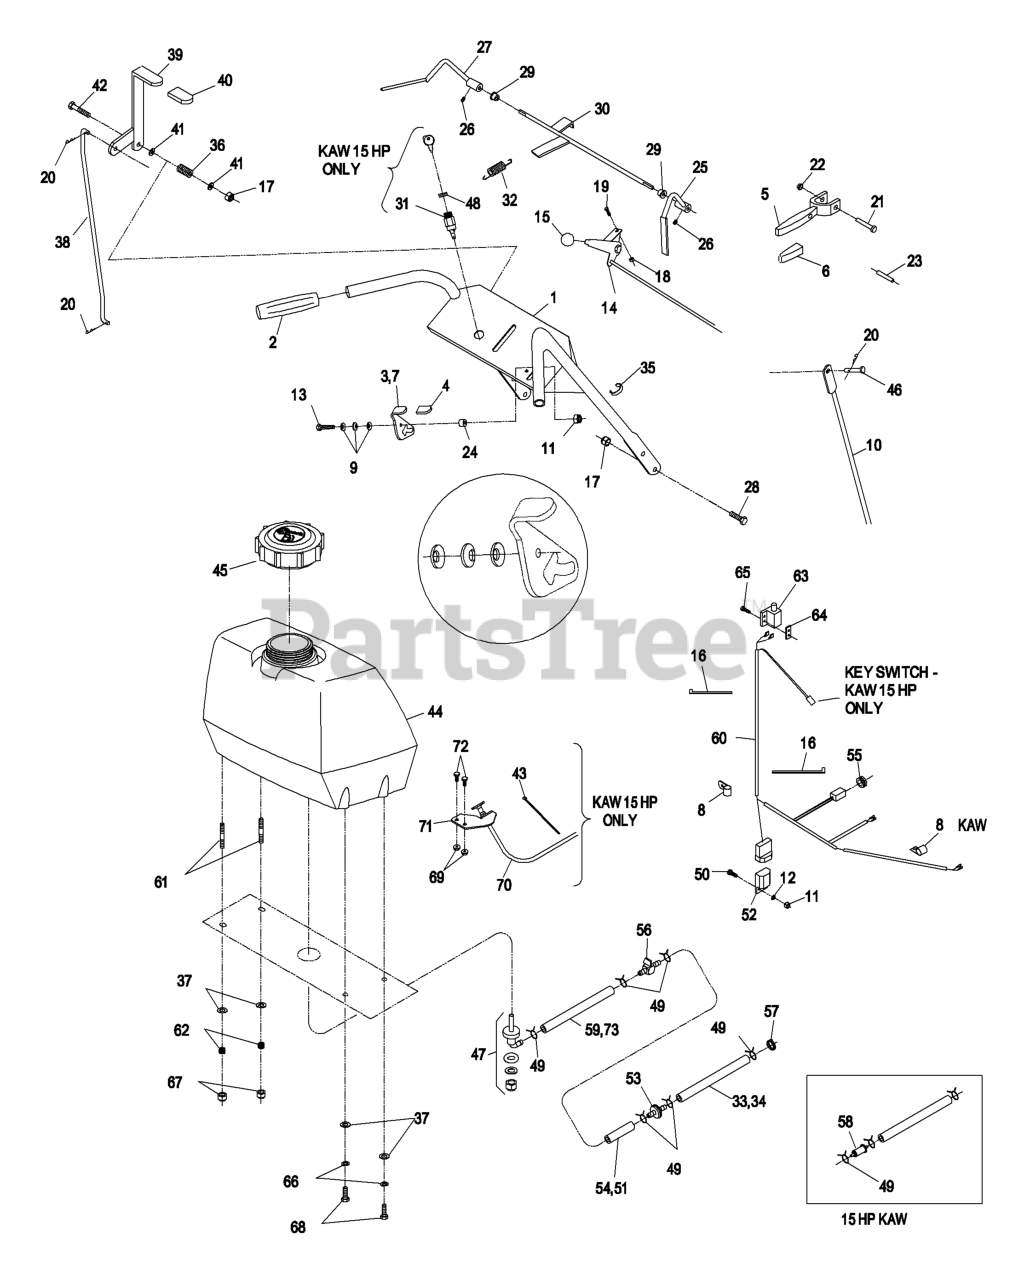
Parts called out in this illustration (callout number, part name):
1	KIT,HANDLE/DECALS METRO
4	GRIP-LATCH
5	DRIVE LEVER ASM
6	GRIP-LEVER, DRIVE
8	CLIP-LOOM
9	WASHER-SPRING
10	LINKAGE-WHEEL, DRIVE
11	NUT-LOCK, NI
12	WASHER-FLAT
13	SCREW-HH
14	CABLE-CONTROL, THROTTLE
15	KNOB-BALL
16	TIE-CABLE
17	NUT-LOCK, NI
18	NUT-LOCK, NI
19	BOLT-CARR
20	PIN-COTTER
21	PIN-LEVER, DRIVE
22	NUT-PUSH
23	PIN-ROLL
25	LEVER-RH
26	SCREW-SET
27	LEVER-LH
28	SCREW-HH
29	BUSHING-NYLON
30	WLD,ROD OPC
31	SWITCH & KEY (INCLUDES NU
32	SPRING-EXTENSION
33	HOSE-FUEL
34	HOSE-LINE, FUEL
35	CLIP-CABLE
36	SPRING-COMPRESSION
37	WASHER-PLAIN
38	LINKAGE-BLADE, UPPER
40	GRIP-LEVER
41	WASHER-FLAT
42	SCREW-HH
43	TIE-PLASTIC
46	PIN-CLEVIS
47	FITTING-FUEL, BULKHEAD
48	NUT-SWITCH, IGNITION
50	SCREW-HH
51	HOSE-FUEL
52	MODULE-INTERLOCK
54	HOSE-LINE, FUEL
55	GROMMET
56	VALVE-FUEL
57	CLAMP-HOSE
58	Kawasaki Pn 41019-1055 W/6" Fuel Line
59	HOSE-FUEL
60	HARNESS-WIRING
61	STUD
62	SPRING-TANK, FUEL
63	SWITCH-OPEN, NORMALLY
64	PLATE-TAPPED
65	SCREW-PPH
66	WASHER-LOCK
67	NUT-LOCK, NI
68	SCREW-HH
70	CABLE-CHOKE
71	BRACKET-CABLE, CHOKE
72	SCREW-HH
73	HOSE-FUEL
